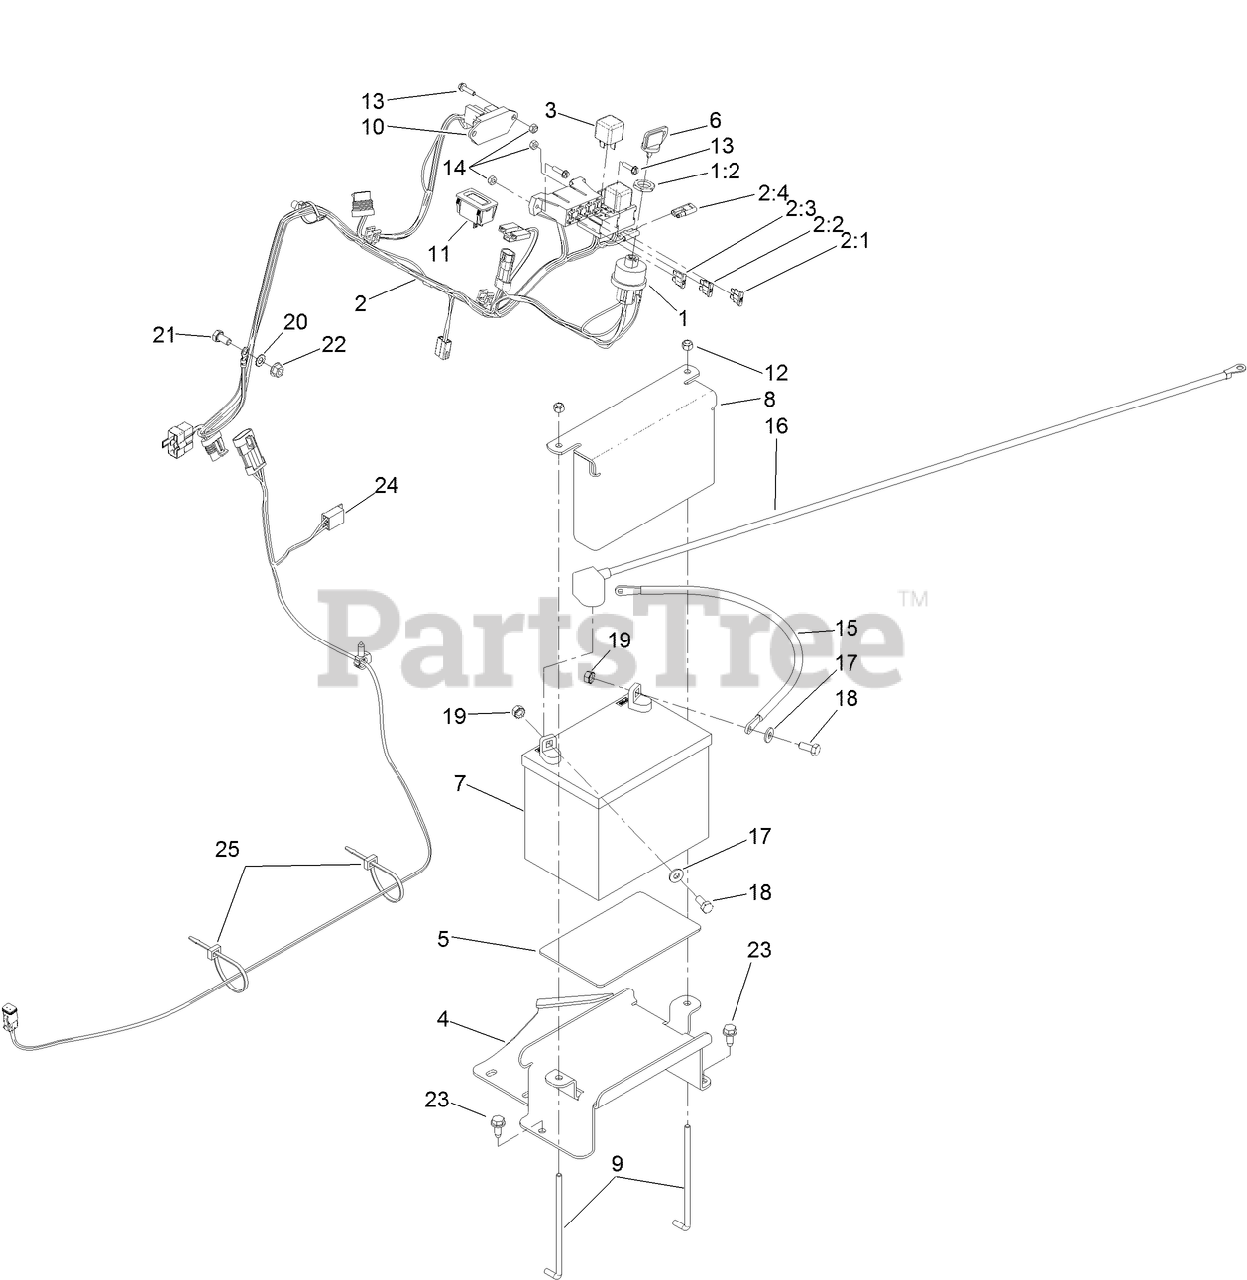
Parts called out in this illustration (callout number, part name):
1	Key Switch ASM
1:2	NUT-HH
2	HARNESS-WIRE
2:1	FUSE-BLADE, 30 AMP
2:2	FUSE-BLADE, 25 AMP
2:3	FUSE-BLADE, 20 AMP
2:4	CAP-PLUG
3	RELAY
4	TRAY-BATTERY
5	PAD-SKID, ANTI
6	KEY-IGNITION
7	BATTERY (340 CCA, WET)
8	PLATE-HOLD DOWN, BATTERY
9	HOLDOWN-BATTERY
10	MODULE-DELAY
11	HOURMETER
12	NUT-LOCK, NI
13	SCREW-HWH
14	NUT-LOCK, NI
15	CABLE-BATTERY, POSITIVE
16	CABLE-BATTERY, NEGATIVE
17	WASHER-FLAT
18	SCREW-HH
19	NUT-KEPS
20	WASHER-LOCK
21	SCREW-HH
22	NUT-HF
23	SCREW-HWHTF
24	HARNESS-WIRE
25	TIE-CABLE
